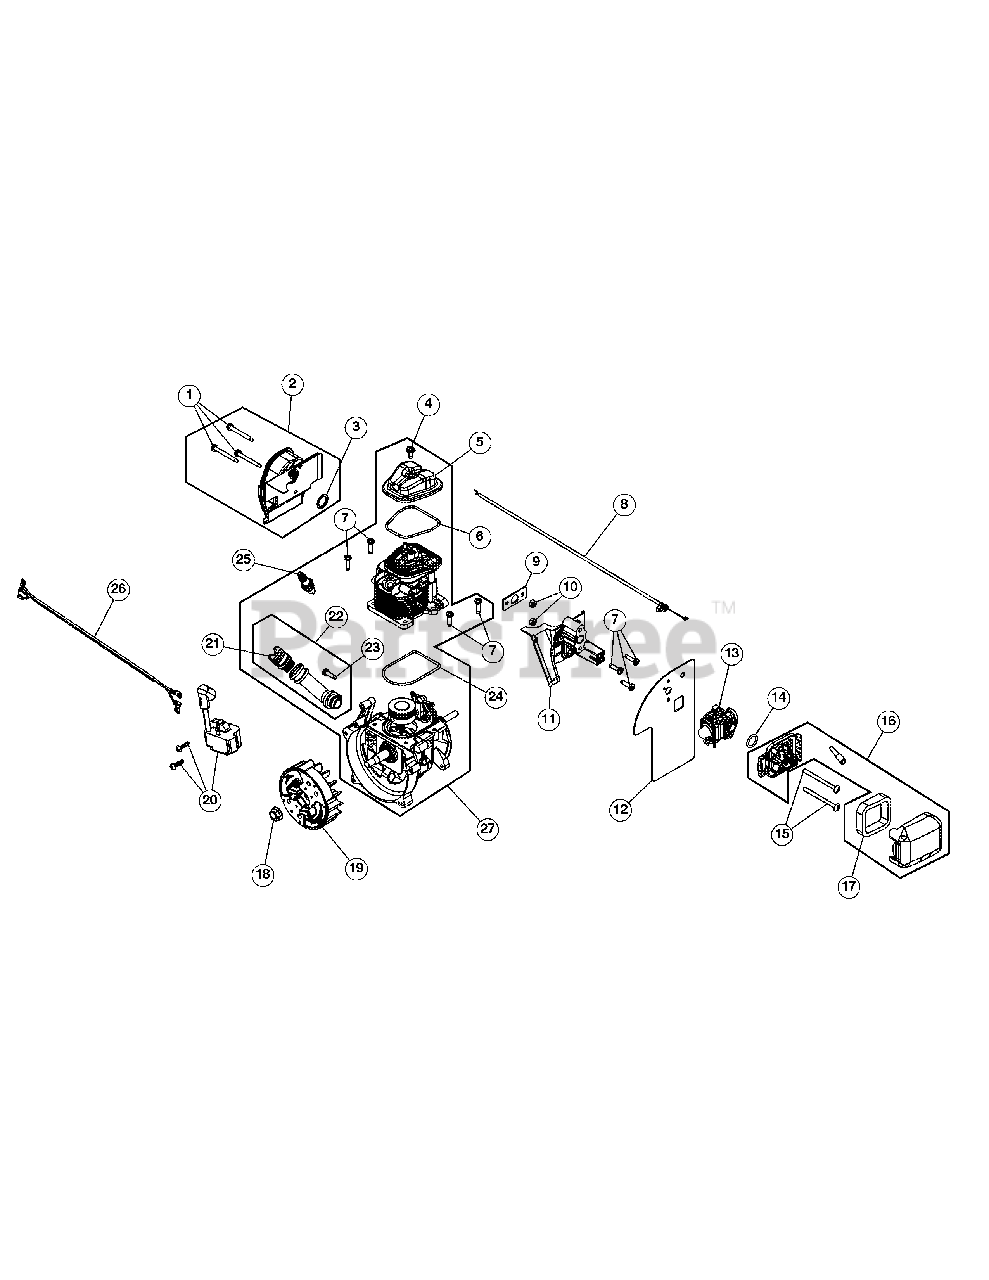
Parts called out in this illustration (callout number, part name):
1	Muffler Screws
2	Muffler Assembly (Incl. 1 & 3)
3	Muffler Gasket
5	Rocker Cover
6	O-Ring
7	Screw
8	Throttle Cable
9	Insulator Gasket
11	Insulator
12	Carburetor Gasket
13	Carburetor
14	Carburetor O-Ring
16	Air Cleaner Assembly (Incl. 17)
17	Air Filter
19	Flywheel Assembly
20	Module
21	Oil Plug
22	Oil Fill Tube (Incl. 23)
24	O-Ring
25	Spark Plug
26	Lead Wire
27	Shortblock Assembly (Incl. 4-7 & 21-25)
